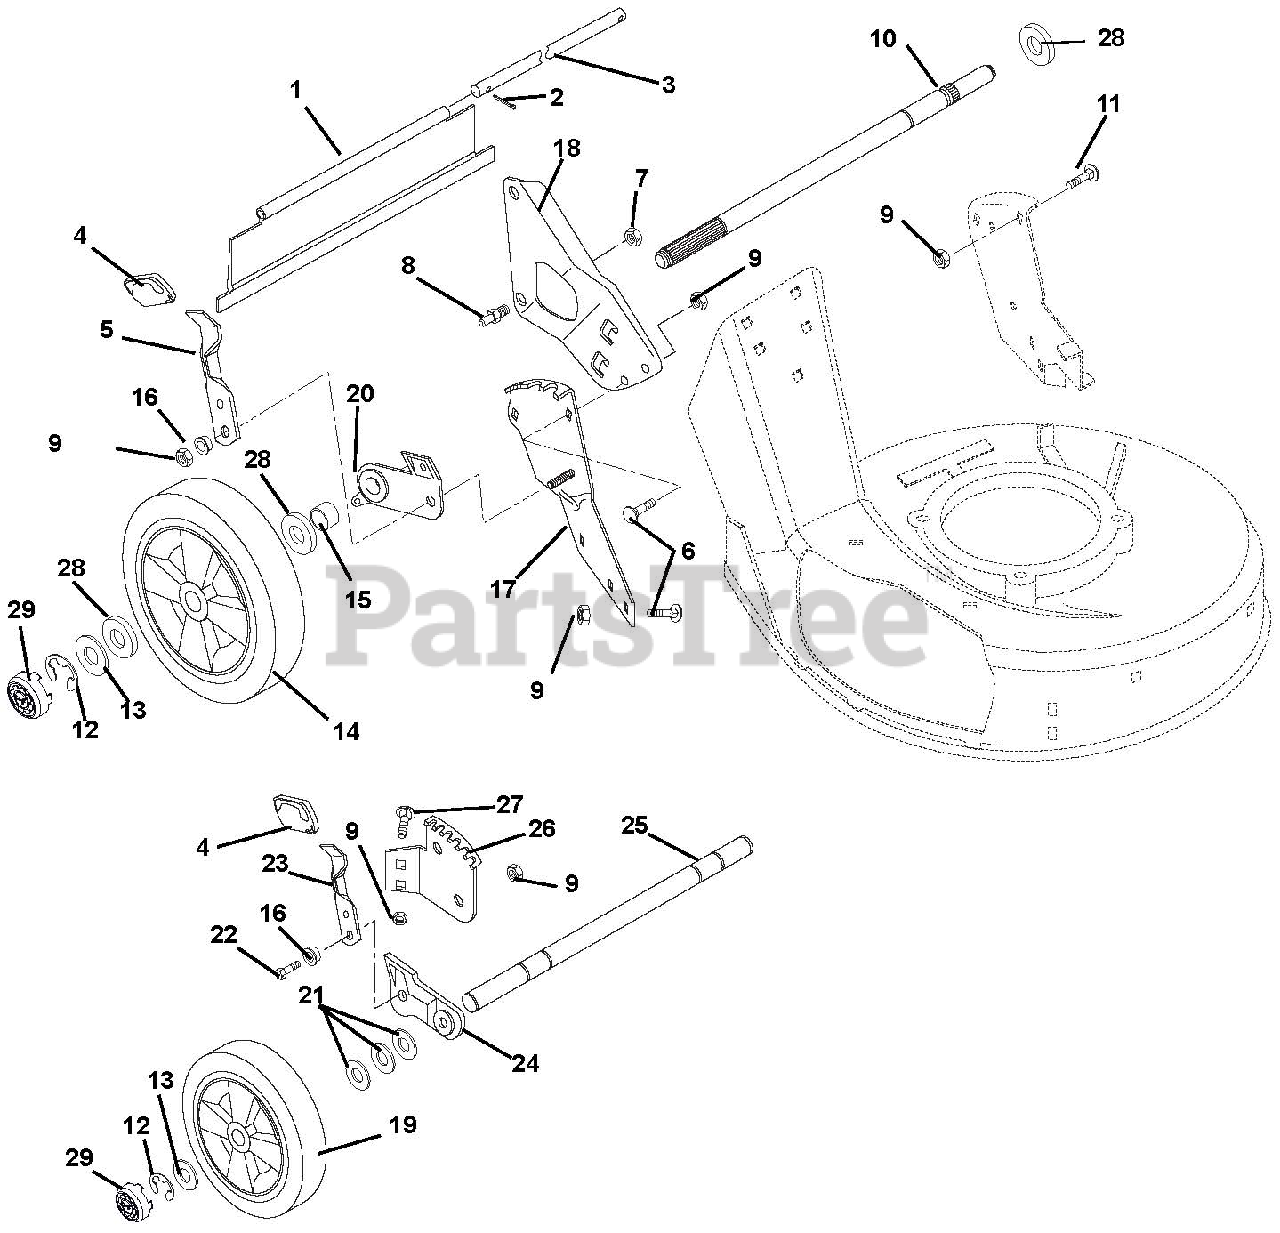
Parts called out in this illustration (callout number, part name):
1	REAR PROTECTIVE GUARD, S.P.
1	REAR PROTECTIVE GUARD, PUSH
2	@PIN-CTR .06X.50 EXTPRSQCT YWZ
4	KNOB
5	LEVER, HEIGHT ADJUSTMENT
6	@BLT-RHDSSQNK .31-18X.62 G5YZ
7	@NUT-LK-CTR .38-16 YWZC
8	HANDLEBAR STUD
9	@NUT-LK-TOP-FLG .31-18 YWZC
10	REAR AXLE,5/8 DIA
10	REAR AXLE-PUSH MOWER MM
11	@BLT-RHDSSQNK .31-18X1.00 G5YZ
12	RG-RTNG-EXT .500X.042 (E)
13	WSHR-FL-STL .505X.880X.072 YWZ
14	WHEEL, ASSEMBLY CLASSIC LM- LH
14	KIT, REAR WHEEL REPLCMNT-PUSH
14	WHEEL, 10.3" O.D X 2" W RHS
15	SPACER TUBE, SELF PROPEL
15	SPACER TUBE PUSH RH
16	BSHG-FLG .32X.500X.344X.880
17	QUADRANT, REAR LH
17	QUADRANT, REAR RH
18	RH HANDLEBAR MTG. BRKT
18	LH HANDLEBAR MTG. BRKT
19	WHEEL, 7.5" OD X 1.75" WIDE
20	REAR BRACKET & BEARING ASSY LH
20	REAR BRACKET & BEARING ASSY RH
20	REAR BRACKET & BEARING ASSEMBL
21	WSHR-FL-STL .52X.827X.062 YWZC
22	@BLT-HEX .31-18X1.00 GR5 YWZC
23	FRONT HEIGHT ADJUSTMENT LEVER
24	LEFT ADJUSTOR BRACKET ASSEMBLY
24	RIGHT ADJUSTOR BRACKET ASSEMBL
25	FRONT AXLE
26	FRONT QUADRANT, LH
26	FRONT QUADRANT, RH
27	@BLT-RDHDSQNK .31-18X.50 G5YZ
28	SPACER .531 X 1.00 X .225
29	HUB CAP, LM WHEEL
30	@NUT-LK-CTR .31-18 YWZC
